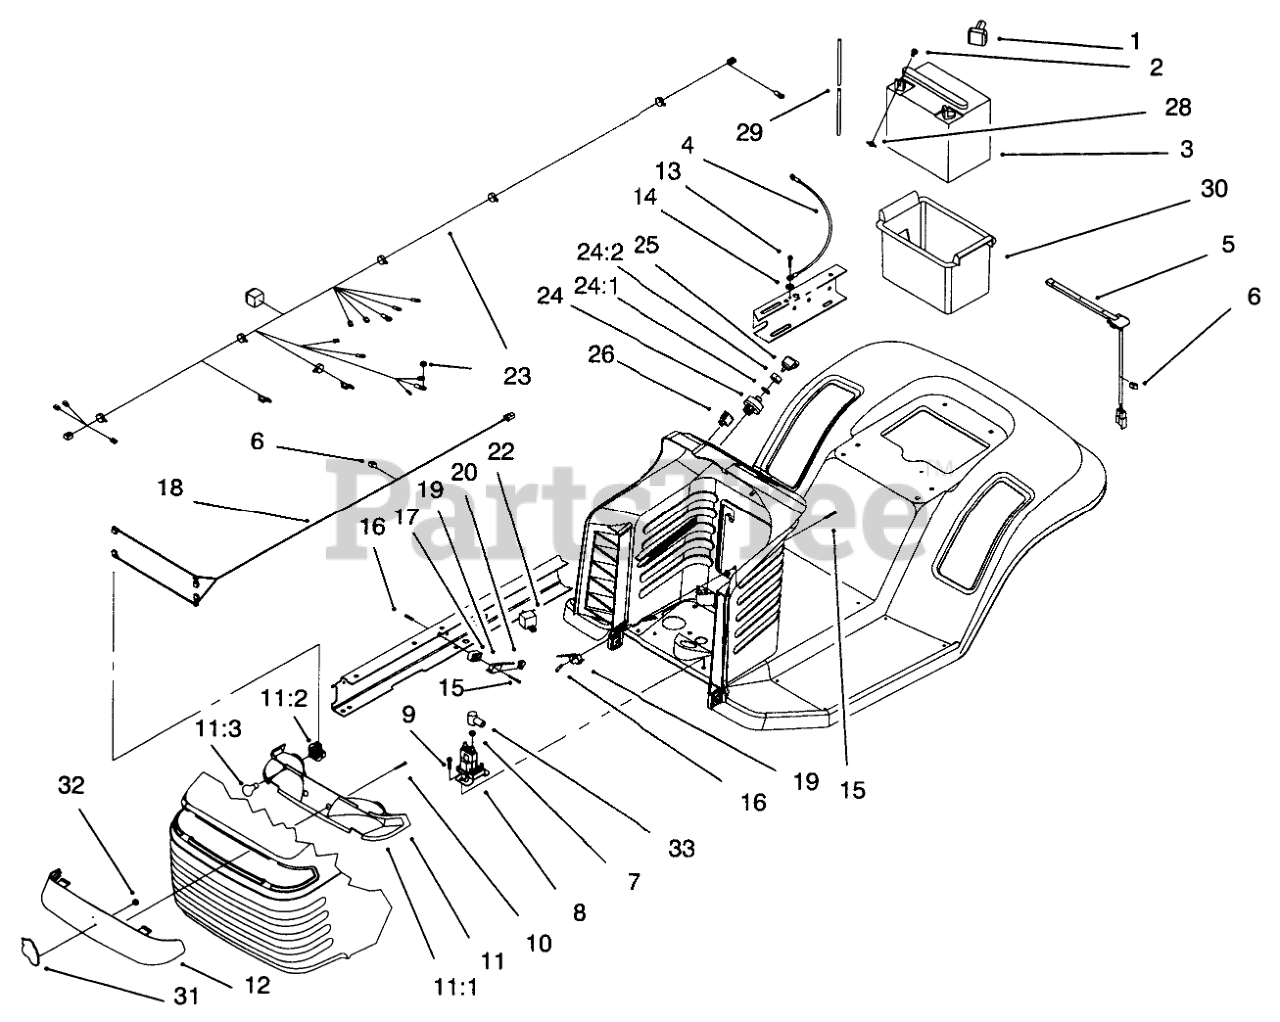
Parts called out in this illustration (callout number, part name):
1	BOOT-TERMINAL
2	SCREW-HH
3	Battery
4	WIRE ASM
5	SWITCH-SEAT
6	CLIP-RETAINER, WIRE
7	NUT-KEPS
8	Solenoid
9	SCREW-HWH
11	Reflector-Lamp (Incl. Ref. #11:2-11:3)
11:2	SOCKET-LIGHT
11:3	BULB
12	LENS-HEADLIGHT
13	SCREW-HWH
14	WASHER-LOCK/EXT
15	SCREW-HH
16	NUT-SPEED
17	SPACER
18	HARNESS-WIRE, LIGHTS
19	SWITCH-MICRO
20	PLUNGER-SEAL
22	RELAY
23	WIRE HARNESS
24	Switch-Ignition (Incl. Ref. #24:1-24:2)
24:1	WASHER-LOCK/INT
24:2	NUT-HH
25	KEY-IGNITION
26	SWITCH-ROCKER
28	NUT-WING
29	TUBE-BATT DRAIN/80-2600
30	BOX-BATTERY
31	EMBLEM-GRILLE WHEELHORSE
33	BOOT-TERMINAL INSULATOR
